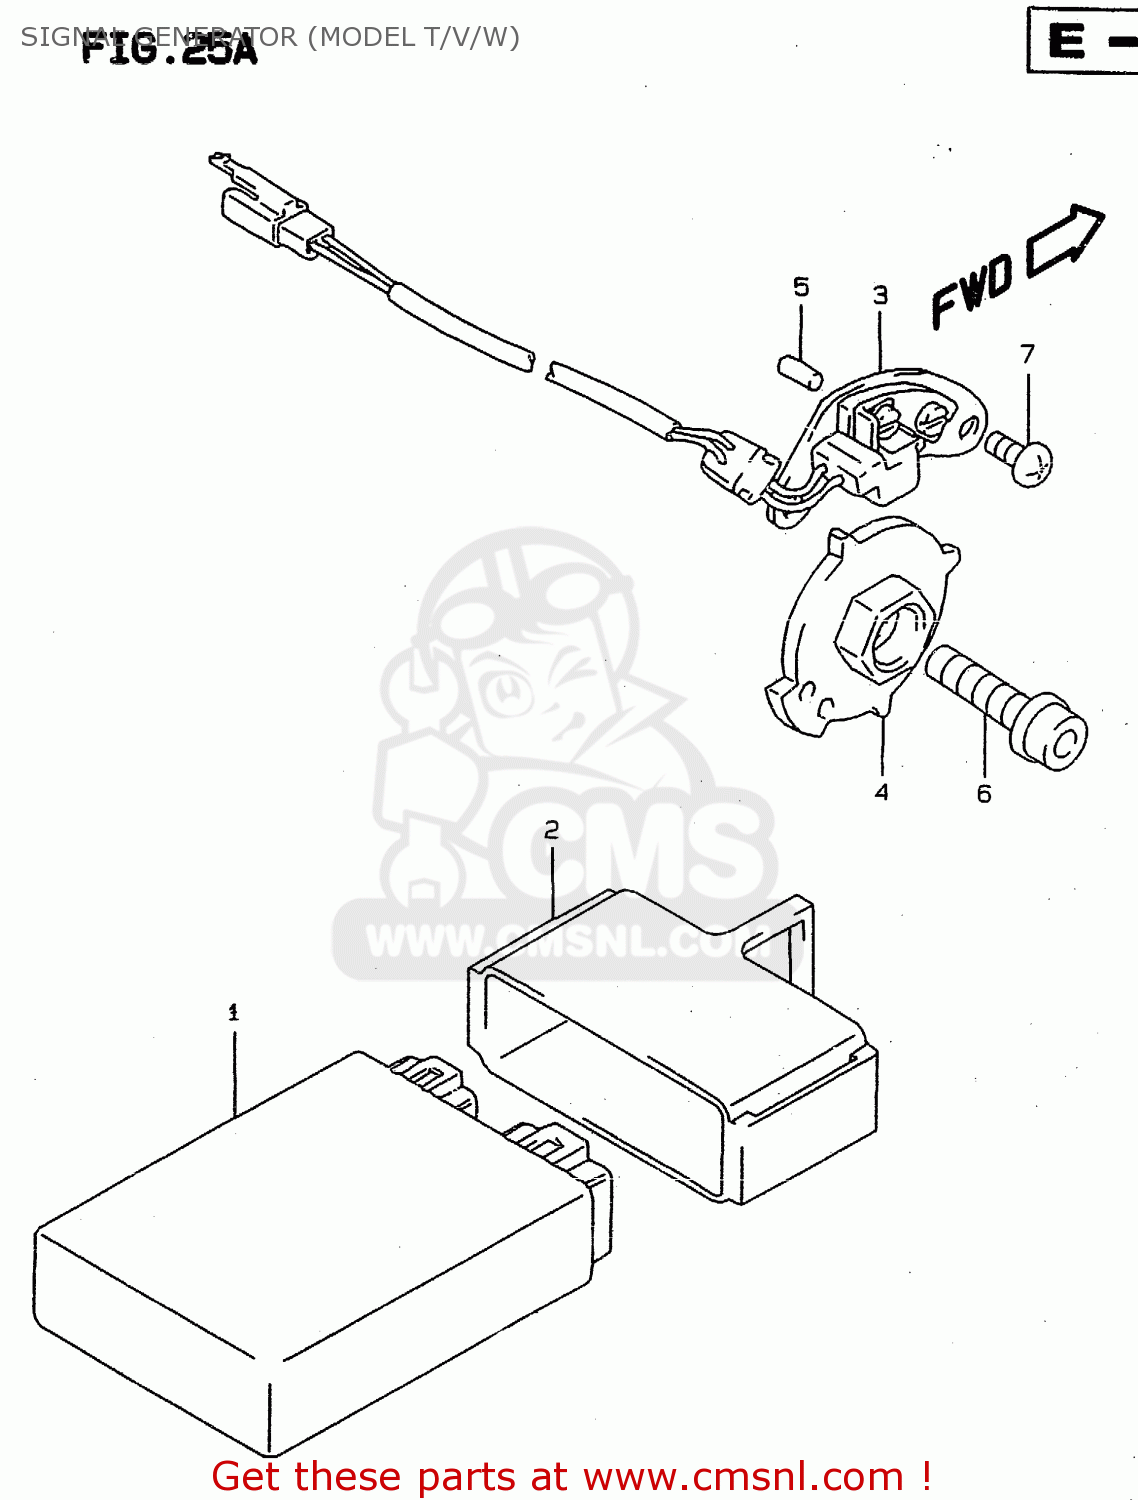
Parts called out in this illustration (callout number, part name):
1	IGNITOR ASSY
2	CUSHION,IGNITOR
3	STARTER,SIGNAL GENERATOR
4	ROTOR,SIGNAL GENERATOR
5	PIN
6	BOLT
7	SCREW
